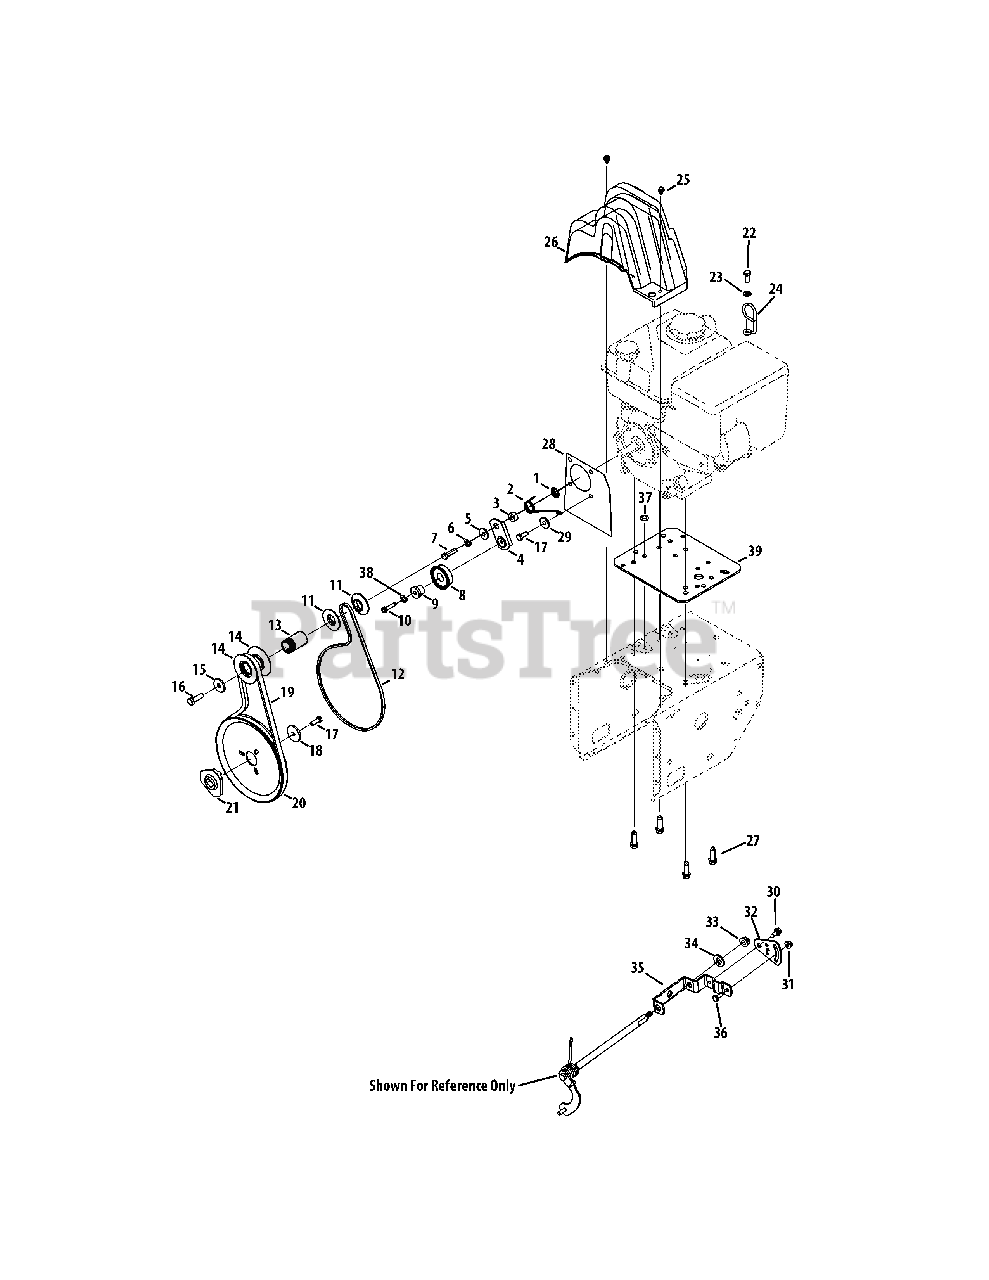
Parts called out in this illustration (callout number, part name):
1	Push-On Nut
2	Torsion Spring, .850 ID x .333
3	Spacer, .340 x .750 x .330
4	Idler Bracket
5	Shldr. Spacer, .3175 ID x .500 x .0975
6	Lock Washer, 5/16
7	Hex Screw, 5/16-24 x 1.25
8	Idler Pulley
9	Shoulder Spacer, .260 x .785 x .538
10	Hex Washer Screw, 1/4-20 x 1.250
11	Pulley Half, 3/8-V x 1.7160 OD
13	Spacer, .875 ID x 1.185 OD
14	Pulley Half, 4L-V x 2.600 OD
15	Flat Washer, .406 x 1.25 x .157
16	Hex Screw, 3/8-24 x 1.25
17	Hex Lock Screw, 5/16-24 x .875
18	Flat Washer, .34 x 1.50 x .150
19	Belt
20	Auger Pulley
21	Adapter Pulley
22	Hex Screw, M8-1.25 x 20
23	Flat Washer, .330 x .630 x .0635
24	Cable Control Wire
25	Hex Washer Screw, 1/4-20 x .375
26	Belt Cover
27	Hex Washer Screw, 3/8-16 x 1.250
28	Cover Plate
29	Shoulder Spacer
30	Shoulder Screw, .368 x .113 x 1/4-20
31	Flange Lock Nut, 1/4-20
32	Speed Selector Pivot Bracket
33	Flange Lock Nut, 5/16-18
34	Flat Washer, .469 x .875 x .105
35	Speed Selector Shift Bracket
36	Hex Screw, 1/4-20 x .620
37	Plug, 3/8 ID
38	Lock Washer, 1/4
39	Engine Plate
